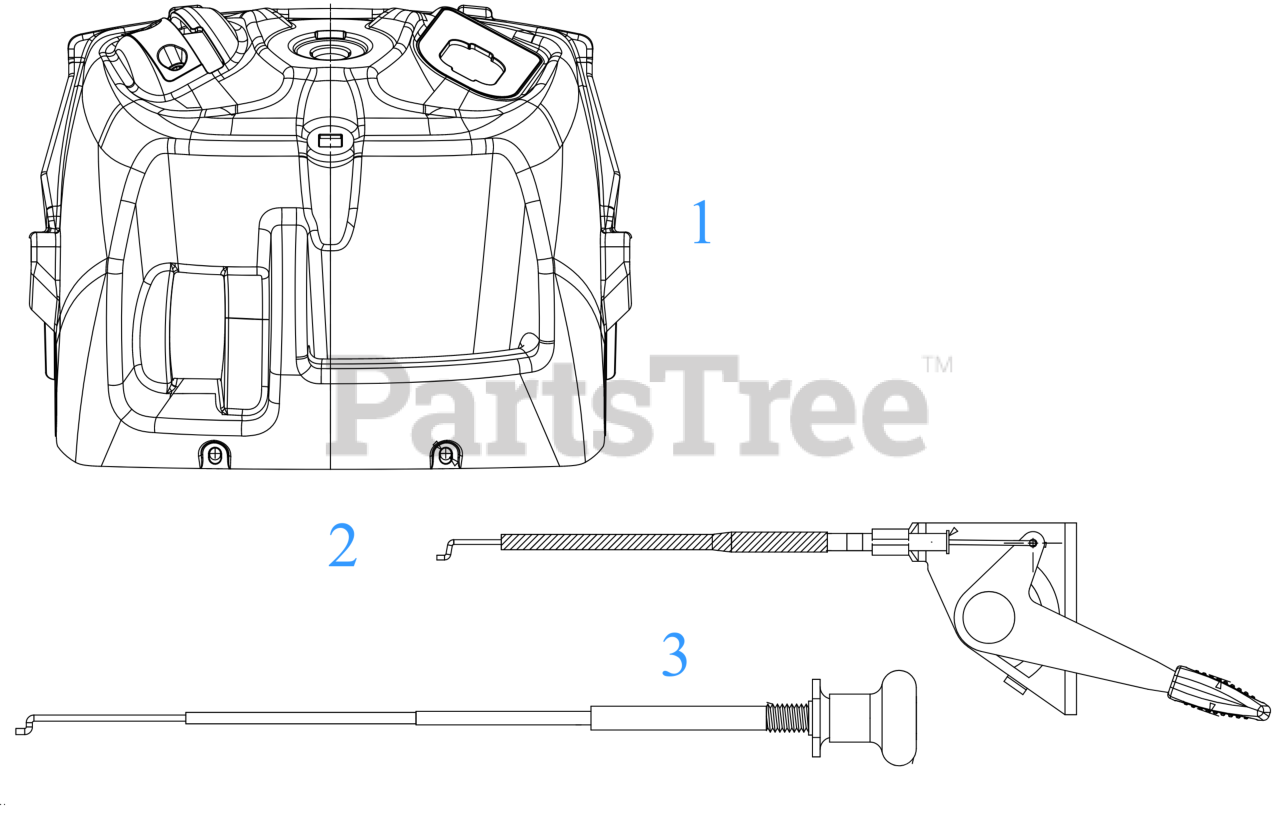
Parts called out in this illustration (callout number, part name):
1	UPPER DASH
2	THROTTLE CABLE 41.5 x .62
3	40.5" CHOKE CABLE
